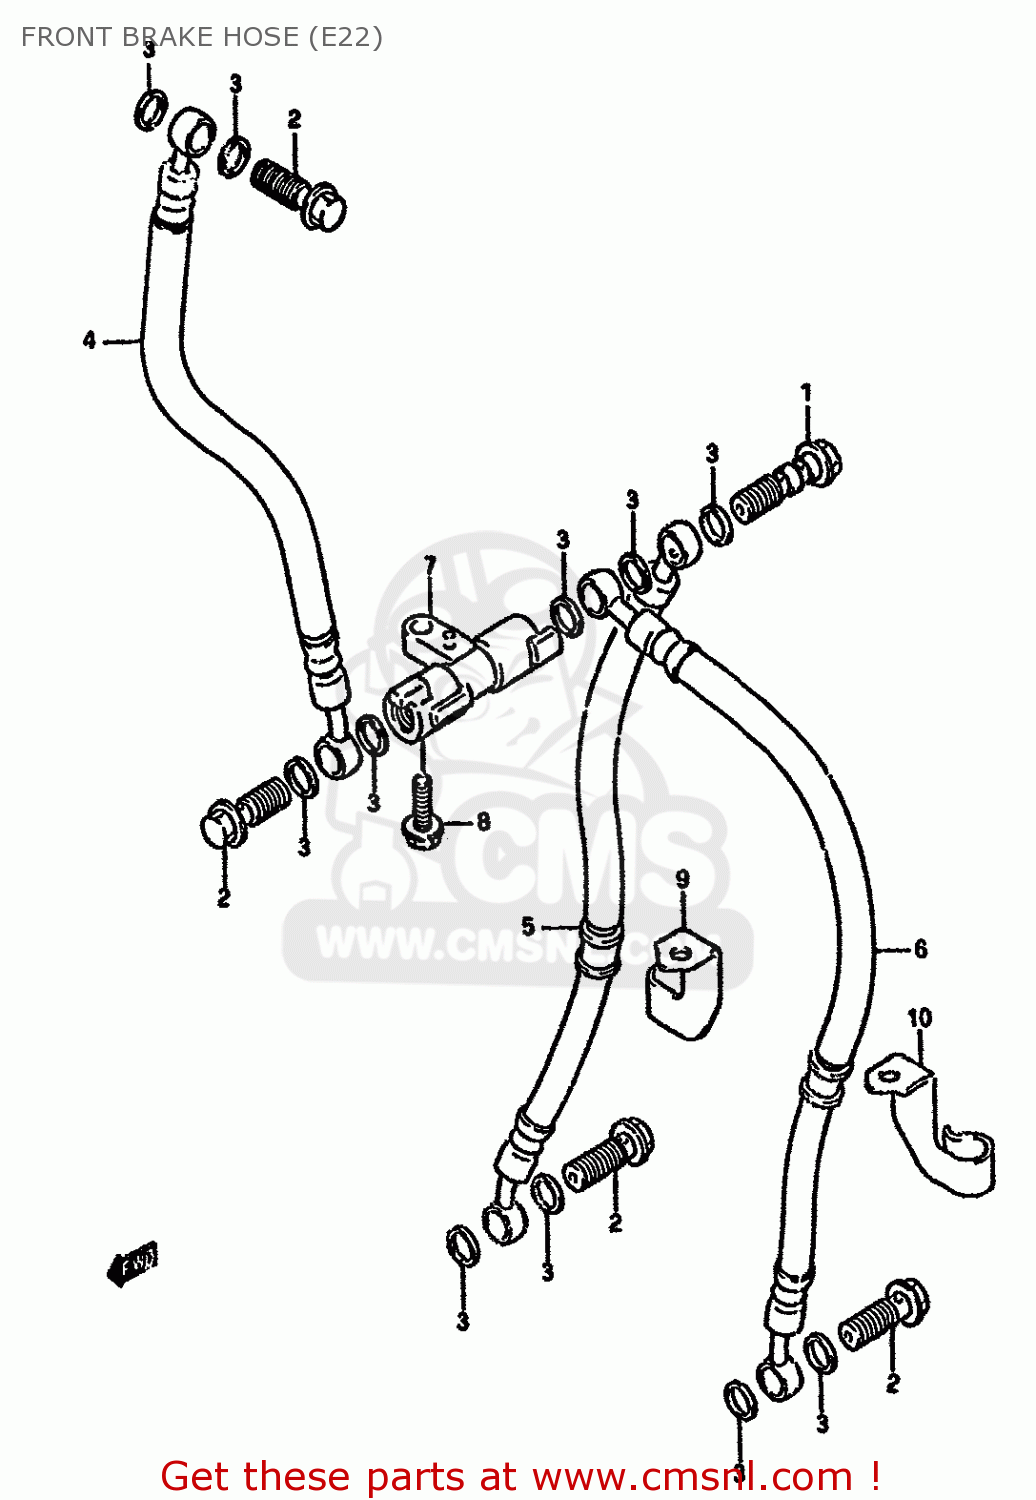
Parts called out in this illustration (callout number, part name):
1	BOLT UNION
2	BOLT UNION
3	WASHER(10X15X1.5)
4	HOSE,FR BRAKE NO.1
5	HOSE,FRONT BRAKE NO.2 RH
6	HOSE,FRONT BRAKE NO.2 LH
7	JOINT,BRAKE HOSE
8	BOLT 6X16
9	CLAMP,FR BRAKE HOSE,R
10	CLAMP,FR BRAKE HOSE,L
